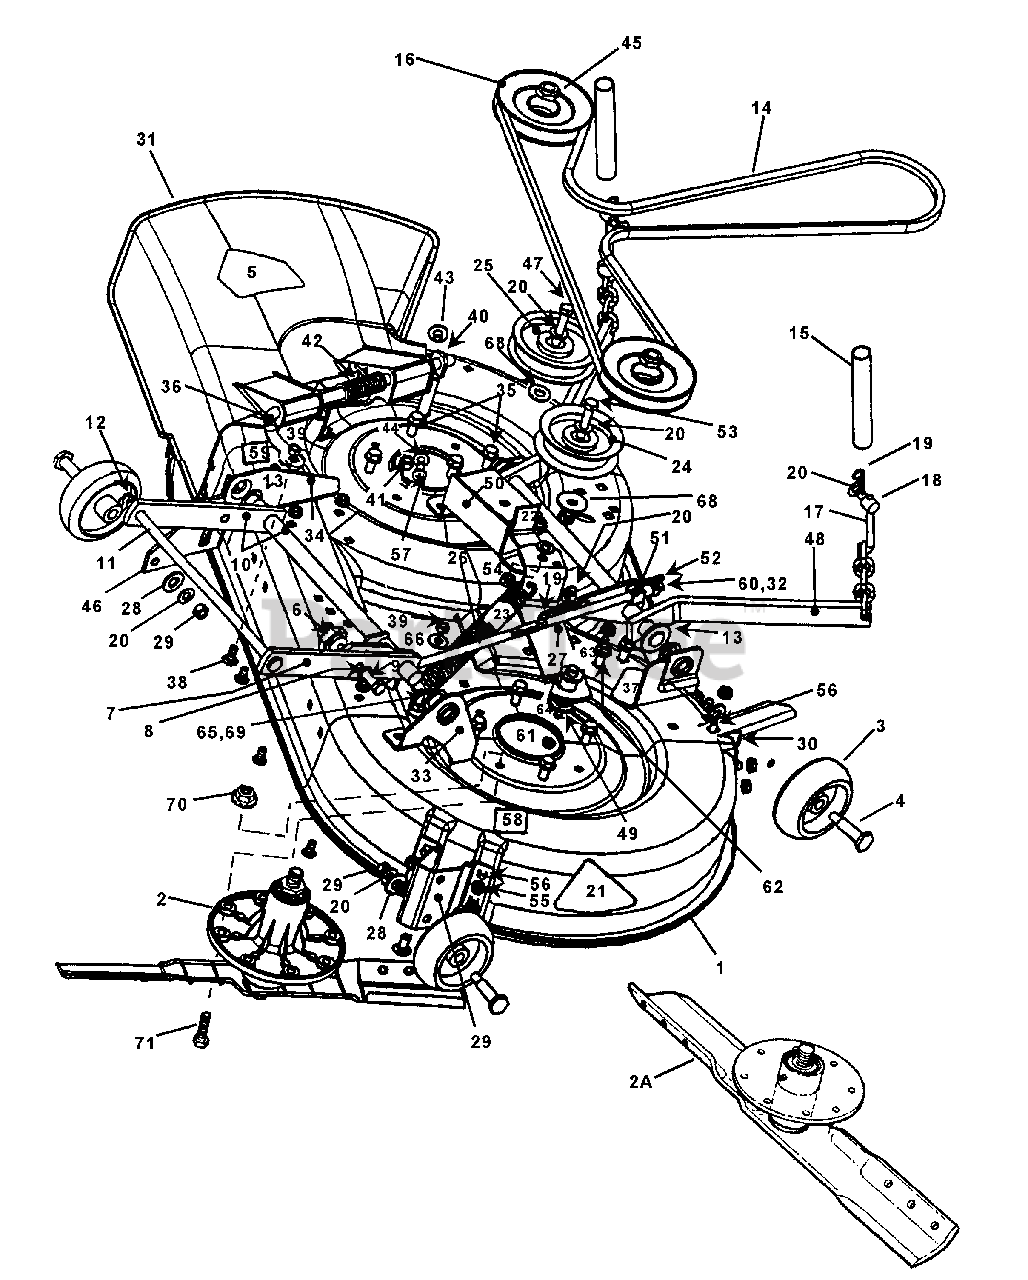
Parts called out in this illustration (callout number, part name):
1	DECK, 38"
2	ASSEMBLY, Spindle
2A	ASSEMBLY, Spindle
3	WHEEL 4 x 1-1/2" Offset
4	BOLT, 3/8-24 Shoulder
5	DECAL, CPSC- Heavy Adhesive
6	ECCENTRIC, Leveling
7	LIFT ARM, Front
8	WASHER, 3/8" Internal Tooth Lock
9	SCREW, 3/8-24 x 1-1/4" Hex Head Cap. Grade 5
10	LIFT ARM, Front
11	ROD, Deck Support
12	RING, .438 External Retaining
13	WASHER, 3/4" I.D. x 1-1/8" Flat
14	V-BELT, HA Section
15	COVER, Chain
16	PULLEY, 4-1/2" O.D. A/B Groove
17	ADJUSTER, Chain
18	SWIVEL, Adjustable
19	HAIR PIN, 3/32 x 1-1/2"
20	WASHER, 3/8" Flat
21	DECAL, 38 Inch
22	BELT GUIDE, 38/42
23	SPRING, Extension
24	IDLER, 4" O.D. Flat
25	IDLER, 4-1/8" O.D. Flat
26	ROD, Cutter Deck Timing
27	ARM, Idler
28	WASHER, 1/2" x 1-1/16" Flat
29	BRACKET, Gage Wheel
30	BRACKET, L.H. Wheel
31	CHUTE, Discharge
32	SPACER, 25/64"
33	BRACKET, 38 Deck Lift, L.H. Front
34	BRACKET, 38 Deck Lift, R.H. Front
35	SCREW, 3/8-16 x 3/4" Hex Washer Self-Tap
36	ROD, Pivot, Side Discharge
37	BRACKET, L.H. Rear Lift Arm
38	BOLT, 5/16-18 x 3/4" Carr. Grade 5
39	NUT, 5/16-18 Hex Center Lock, Grade 5
40	ROD, Mounting, Side Discharge
41	NUT, 3/8-16 Hex Flange Lock
42	SPRING, Torsion- Side Discharge
43	TEENUT, 5/16-18 Thread
44	WASHER, 5/16" I.D. x 11/16" Flat
45	NUT, 5/8-18 Lock
46	BRACKET, Gage Wheel
47	SCREW, 3/8-16 x 2", Hex Head Cap, Grade 5
48	TIMING ARM, Rear
49	STUD, Idler
50	BRACKET, Stationary Idler
51	SWIVEL, Brake Link
52	HAIR PIN, #13
53	SCREW, 3/8-16 x 1-3/4" Hex Head Cap, Grade 5
54	NUT, 3/8-16 Hex Ctr Lock, Gr. 5
55	NUT, 5/16-18 Hex Flange Lock, Grade 5
56	BOLT, 5/16-18 x 5/8" Carriage, Grade 5
57	SCREW, 5/16-18 x 5/8" Pan Head
58	DECAL, Caution
59	DECAL, Caution
60	NUT, 3/8-16 Hex Ctr. Lock, Grade 5
61	NUT, 5/16-24 Hex Center Lock
62	BOLT, 3/8-16 x 3/4" Carr., Gr. 5
63	WASHER, 1/2" I.D. x 1-1/16" O.D. Flat
64	COTTER-PIN, 3/32 x 3/4"
65	BOLT, 5/16-18 x 1-1/2" Carr., Gr. 5
66	WASHER, 3/8" I.D. x 7/8" O.D. Flat
68	WASHER, Cone
69	SPACER, 11/32"
70	NUT, 5/16-18 Hex Flange Lock
71	SCREW, 5/16-18 x 1" Hex Cap
